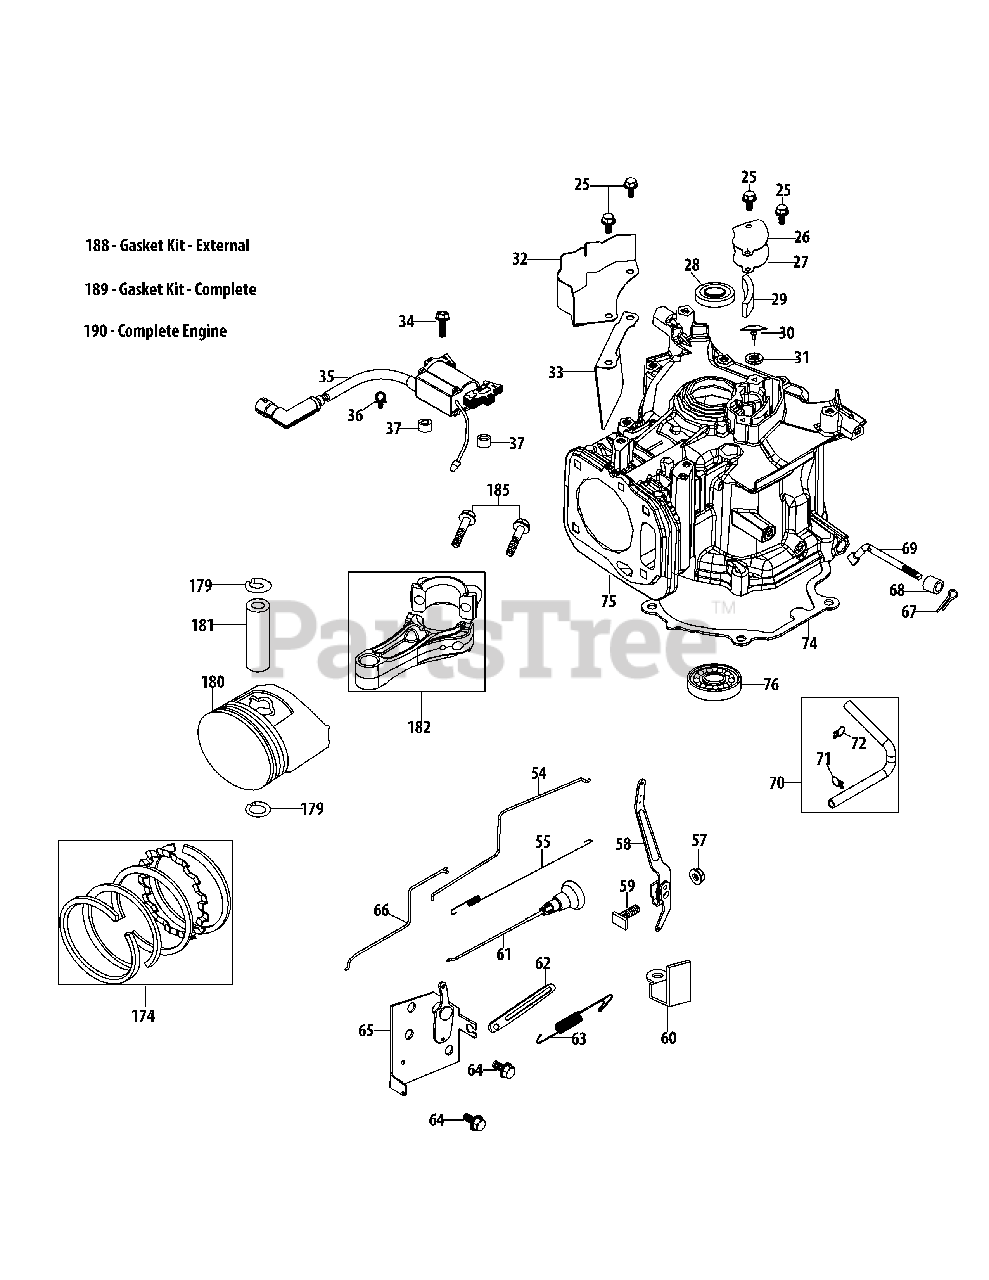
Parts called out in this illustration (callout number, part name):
25	Bolt M6X14
26	Breather Cover Plate
27	Breather Gasket
28	Upper Crankshaft Seal
29	Breather Screen
30	Breather Valve
31	Breather Valve Base
32	Engine Brake Cover Plate
33	Label Bracket
34	Bolt M6X30
35	Ignition Coil Assembly
36	Ignition Wire Clip
37	Ignition Coil Spacer
54	Throttle Linkage
55	Throttle Linkage Spring
57	Governor Arm Nut M6
58	Governor Arm
59	Governor Arm Bolt
60	Governor Arm Guard
61	Choke Control
62	Flexible Clamp
63	Governor Spring
64	Bolt M6X12
65	Component Bracket
66	Choke Linkage
67	Governor Arm Shaft Cotter Pin
68	Governor Seal
69	Governor Arm Shaft
70	Breather Hose Assembly
71	Breather Hose Clamp
72	Breather Hose Clamp
74	Crankcase Cover Gasket
75	Short Block Assembly
76	Main Bearing
174	Piston Ring Set
179	Piston Pin Snap Ring
180	Piston
181	Piston Pin
182	Connecting Rod Assembly
185	Connecting Rod Bolt
188	Gasket Kit - External
189	Gasket Kit - Complete
190	Complete Engine
